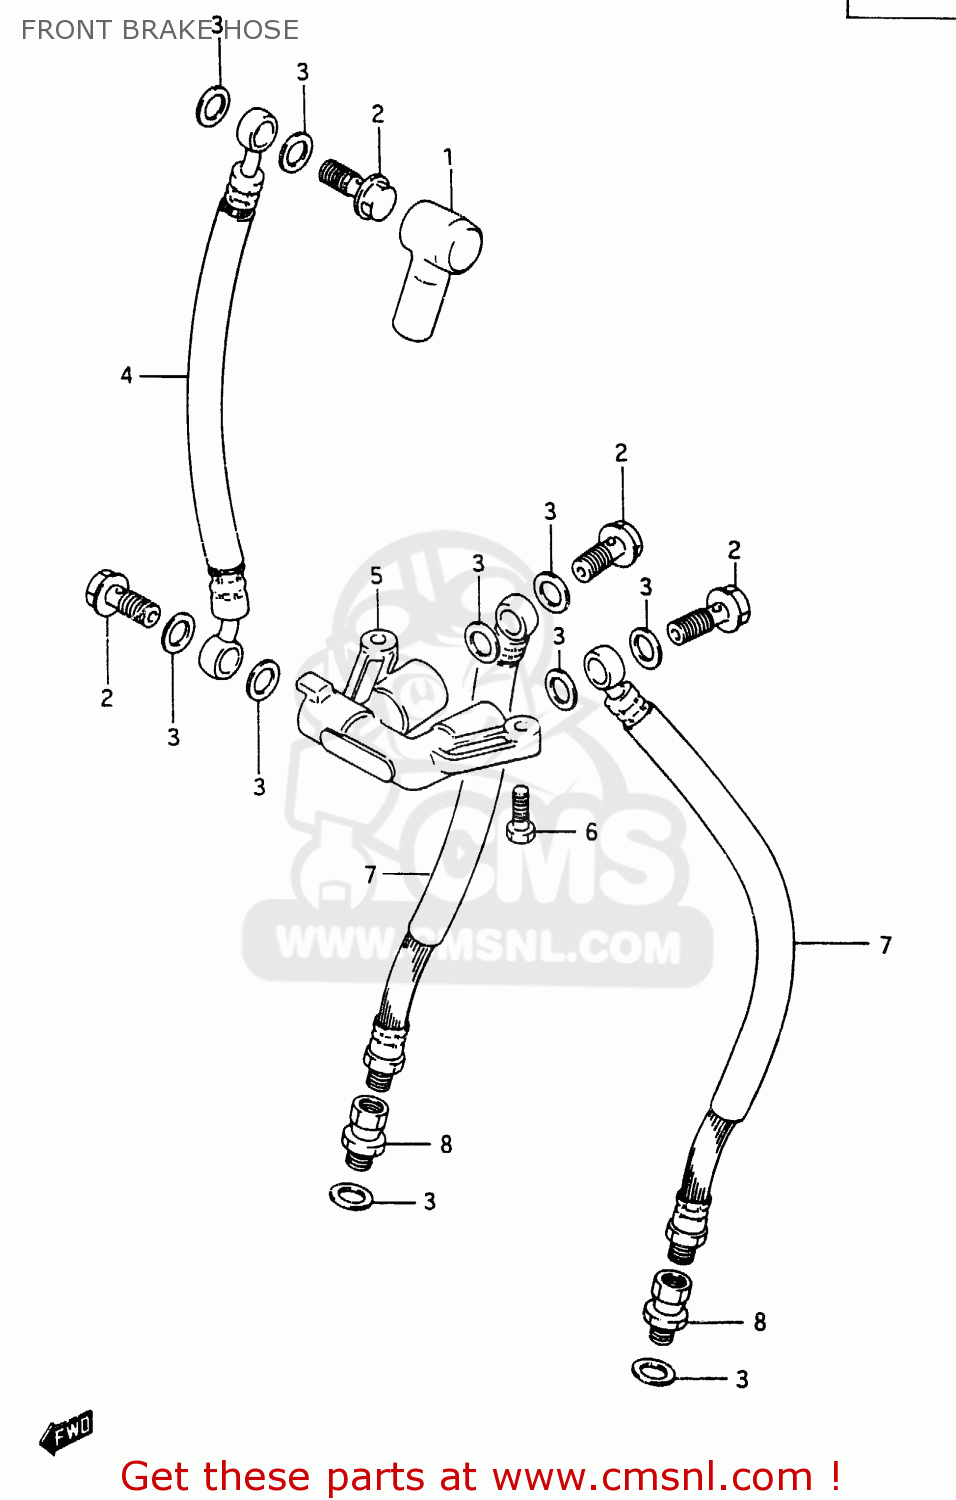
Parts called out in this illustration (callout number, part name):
1	BOOT
2	BOLT UNION
3	WASHER(10X15X1.5)
4	HOSE, FRONT BRAKE NO.1
5	JOINT, BRAKE HOSE
6	BOLT(6X20)
7	HOSE, FRONT BRAKE
8	ADAPTER,BRAKE HOSE
